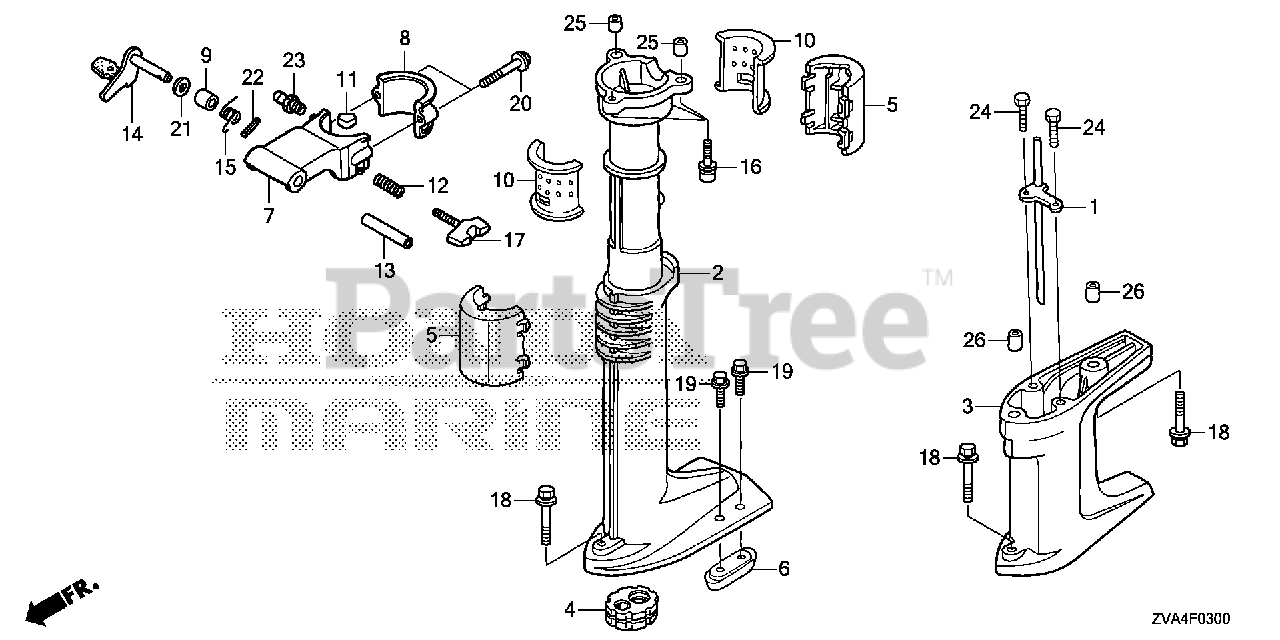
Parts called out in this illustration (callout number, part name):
1	TUBE, WATER
2	CASE, EXTENSION *NH246* (LOOSY GRAY)
3	SEPARATOR, EXTENSION *NH246* (LOOSY GRAY)
4	BUSH, VERTICAL SHAFT (L)
5	PROTECTOR, EXTENSION
7	CASE, SWIVEL *NH246* (LOOSY GRAY)
8	CAP, SWIVEL CASE *NH246* (LOOSY GRAY)
9	COLLAR, SWIVEL CASE
10	LINER, SWIVEL CASE
11	BLOCK, FRICTION
12	SPRING, FRICTION ADJUSTING
13	COLLAR, DISTANCE
14	ARM, TILT LOCK
15	SPRING, TILT LOCK
16	BOLT-WASHER, SOCKET (6X30)
17	BOLT, SWIVEL CASE
18	BOLT-WASHER (6X35)
20	BOLT, FLANGE (8X35)
21	WASHER, PLAIN (8MM)
22	PIN, SPRING (2.5X20)
23	NIPPLE, GREASE
24	BOLT, HEX. (5X16)
25	PIN A, DOWEL (8X10)
26	PIN A, DOWEL (8X14)
